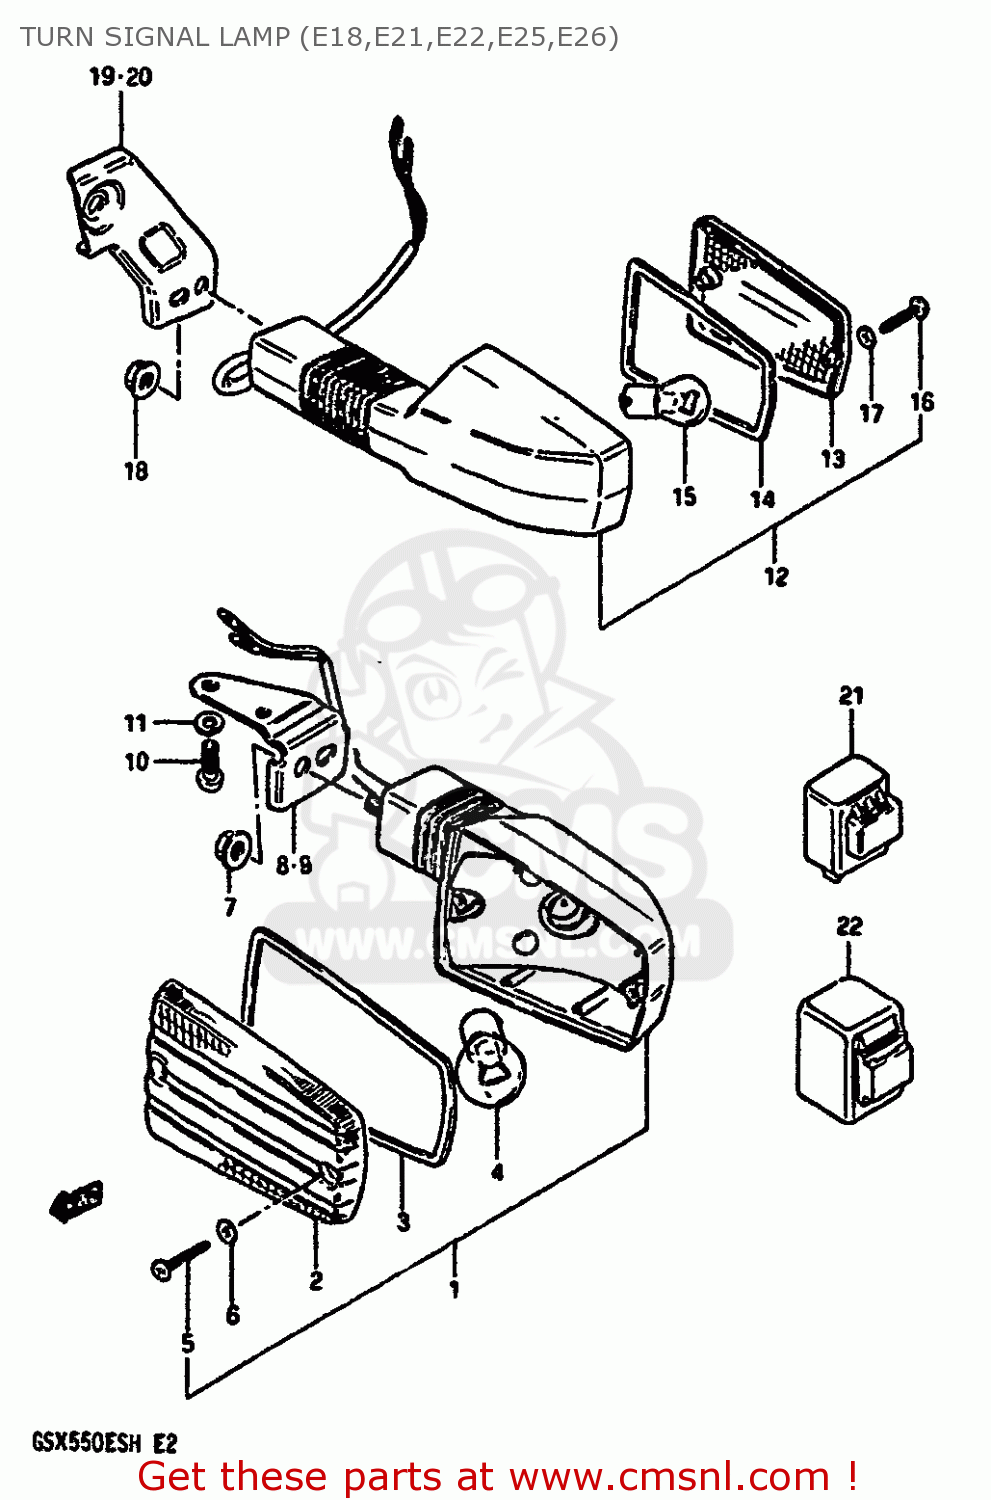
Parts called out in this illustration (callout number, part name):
1	LAMP ASSY, FRONT TURN SIGNAL
2	LENS
3	GASKET (NAS)
4	BULB(12V21W)
5	SCREW
6	GASKET (NAS)
7	NUT M8
8	BRACKET,FRONT TURN SIGNAL
9	BRACKET,FRONT TURN SIGNAL
10	SCREW
11	WASHER,LOCK
12	LAMP ASSY, REAR TURN SIGNAL
13	LENS,TURN SIGN
14	GASKET (NAS)
15	BULB(12V21W)
16	SCREW
17	GASKET (NAS)
18	NUT
19	BRACKET,REAR TURN SIGNAL
20	BRACKET,REAR TURN SIGNAL
21	RELAY ASSEMBLY,TURN SIGNAL
22	RELAY ASSY,TUR
